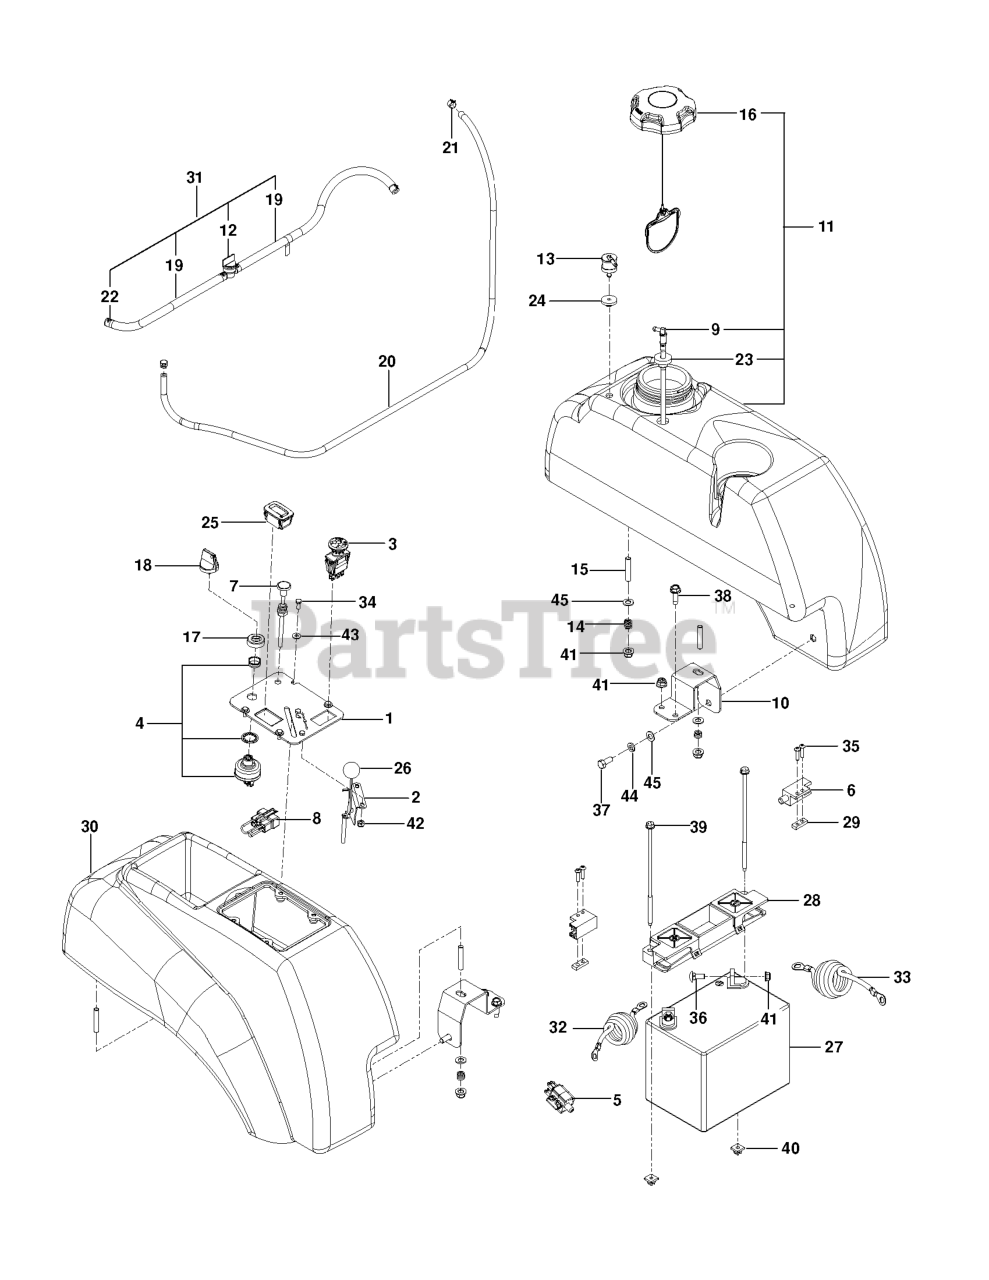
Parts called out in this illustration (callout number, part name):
1	PLATE.CONSOLE.BLACK
2	THROTTLE CABLE
3	SWITCH, PTO 10 AMP
4	SWITCH, IGNITION, INDAK
5	SWITCH, BRAKE 3P
6	SWITCH INTERLOCKT
7	CHOKE CABLE
8	PLUG, TIMER
9	FITTING, FUEL
10	SUPPORT, TANK, BLK
11	TANK FUEL LT ASM MZ GRAY
12	FUEL VALVE
13	VALVE.FUEL.CHECK
15	STUD, 5/16C
16	CAP, FUEL
17	CAP IGNITION NUT
18	KEY, IGNITION
19	GAS LINE 10"
20	HOSE.3/16"VAPOR.27"
21	CLAMP, HOSE
22	HOSE CLAMP
23	RUBBER GROMMET
24	GROMMET, CHECK VALVE
25	RP.GUAGE.SRVCMNDR.HRMTR.
26	KNOB.ROUND.BALL.BLACK
27	BATTERY, 12 V 330 AMP
28	BATTERY HOLD DOWN
29	TAPPED PLATE
30	FENDER CONSOLE
31	FUEL LINE ASM
32	POST.CABLE LONG
33	NEG. CABLE, 28"
34	HCS #10-24 X 1/2
35	SCR #10-24 X .75 SKT HD BLK
36	BOLT 5/16C X 3/4" CARRIAGE
37	HCS 5/16C X 3/4
38	RP BLT 5/16-18 X 1 THRD FORM D
39	BOLT - 1/4-20 X 7.5
40	PUSH NUT-NYLON
41	5/16-18 NYLOC FLANGE NUT
42	NUT 10-24 NYLOC
43	WASHER #10
44	WASHER.LOCK.HVY.HLCL.SPR.5/16
45	FLAT WASHER 5/16 SAE
